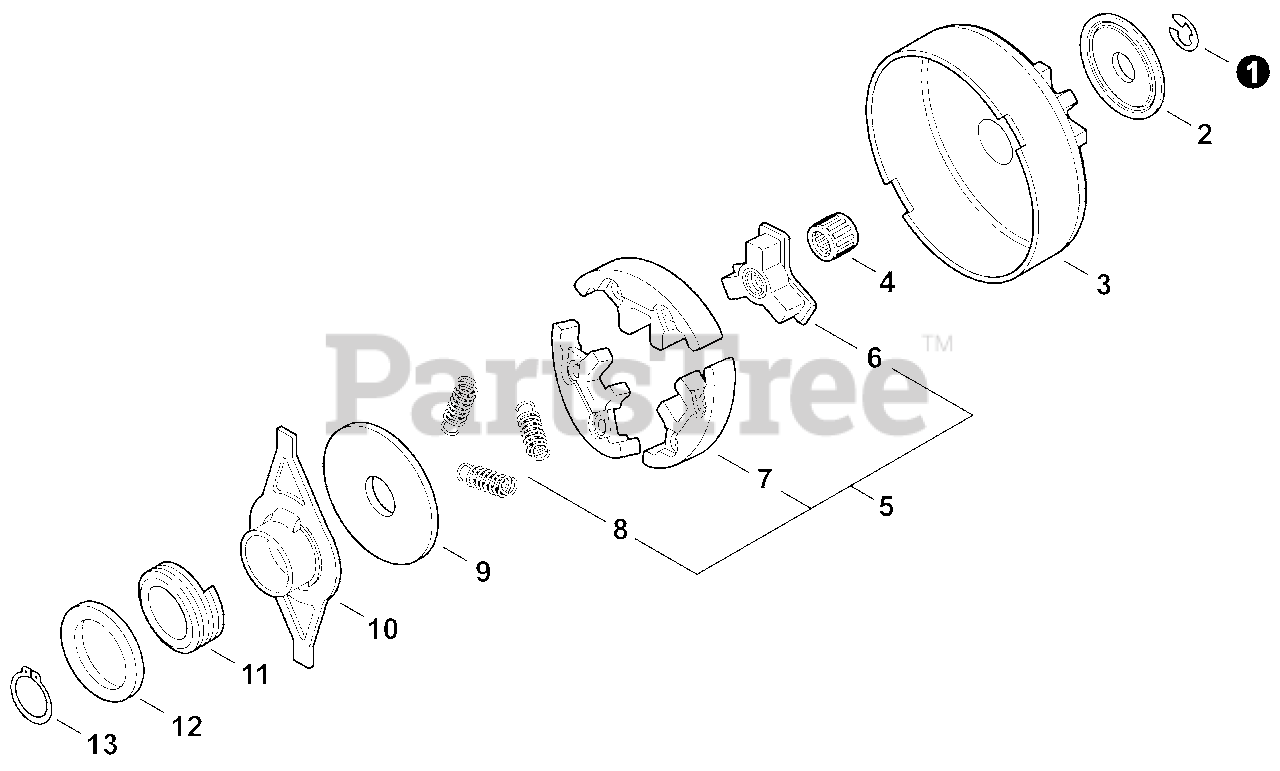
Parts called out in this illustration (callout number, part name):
1	E-RING Ø8.1
2	WASHER 10
3	DRUM, CLUTCH
4	BEARING, NEEDLE 10
5	CLUTCH ASSY
6	HUB, CLUTCH
7	SHOE SET, CLUTCH (3PCS)
8	SPRING, TENSION
9	PLATE, CLUTCH
10	COLLAR 15×19×73
11	GEAR, WORM
12	WASHER 15.5×22.5×0.5
13	RING, RETAINING 15
